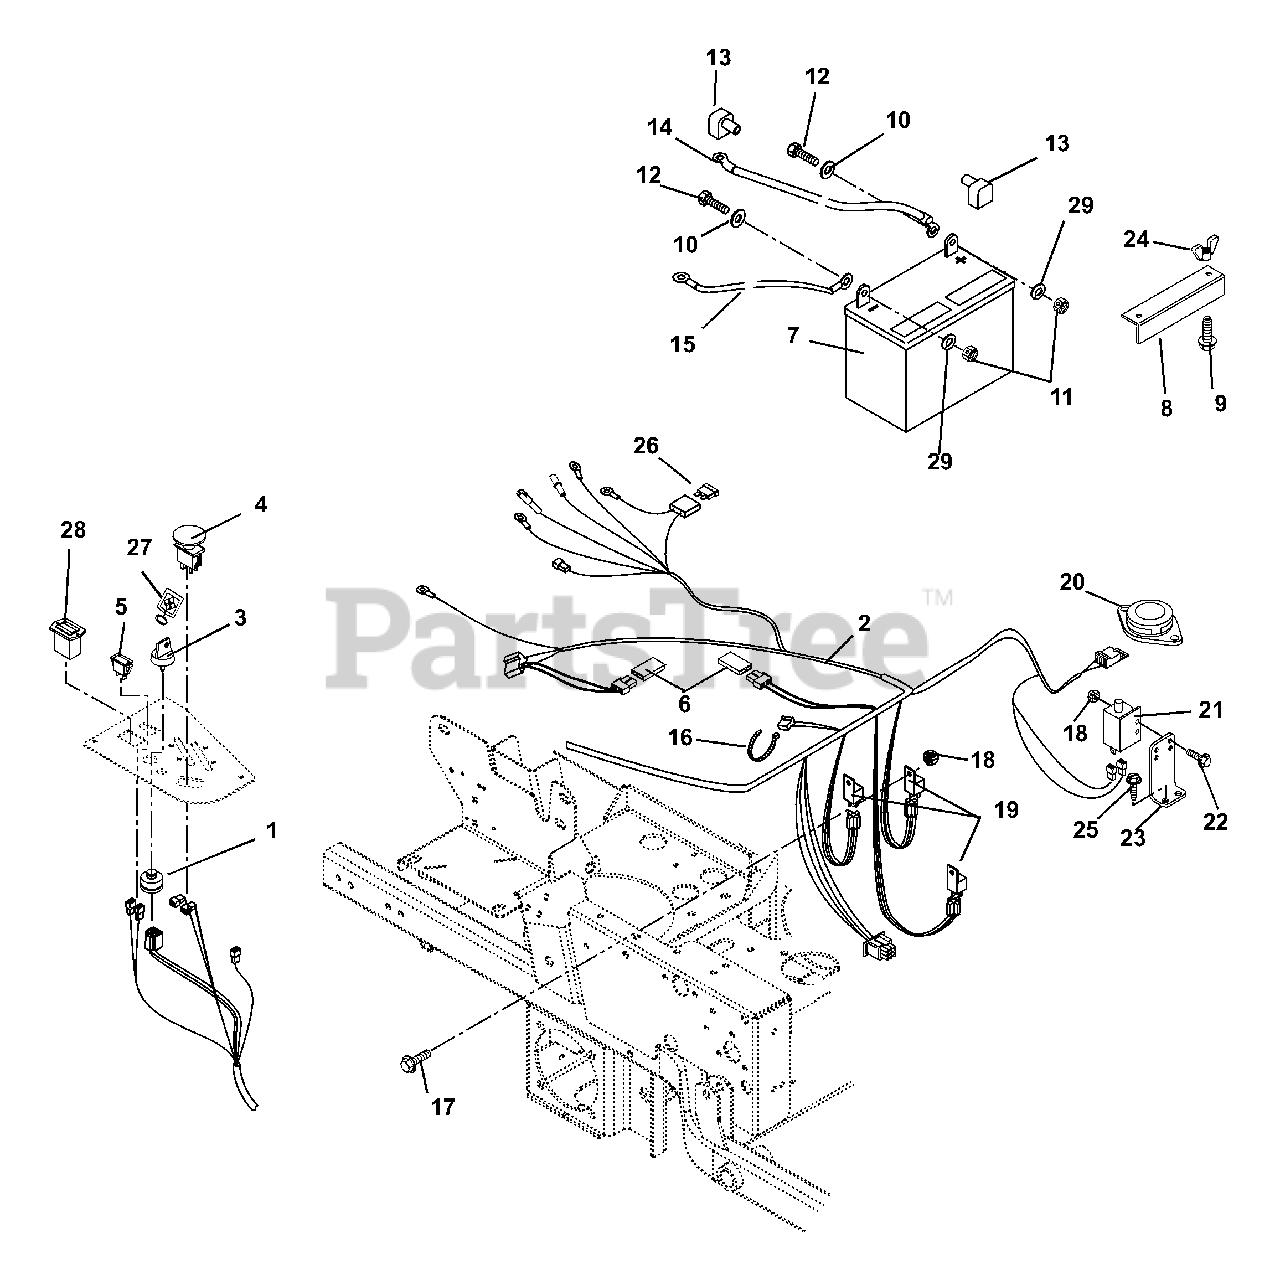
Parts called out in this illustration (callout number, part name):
1	Key Switch
2	Harness, IZ/CZ
3	Key with Shield
4	Switch, Clutch With Retainer Ring
5	Switch, Blank
6	Diode, Connector Shell
8	Hold Down
9	Bolt, Round Head Square Neck .25-20 x 7.50
10	Washer, Flat Steel .281 x .620 x .065
11	Nut, Locking Top Flange .25-20
12	Bolt, Hex .25-20 x .75 Grade 5
13	Insulator
14	Cable, Positive, 26 inch
15	Cable, Negative Battery
16	Cable Tie
17	Screw, Machine 10-24 x .50 Hex Washer Head
18	Nut, Locking Nylon 10-24 With Insert
19	Relay, Sealed with diode
20	Seat Switch
21	Switch, Double Pole N.O./N.O.
22	Screw, Machine 10-24 x .75 Hex Washer Head
23	Mount, Brake Switch
24	Nut, Locking Wing .25-20
25	Screw, Tapping .25-20 x .50 Hex Washer Head
26	Fuse, 30 Amp
27	Key Chain
28	Hour Meter
29	Washer, Locking .25 x .062 Regular
